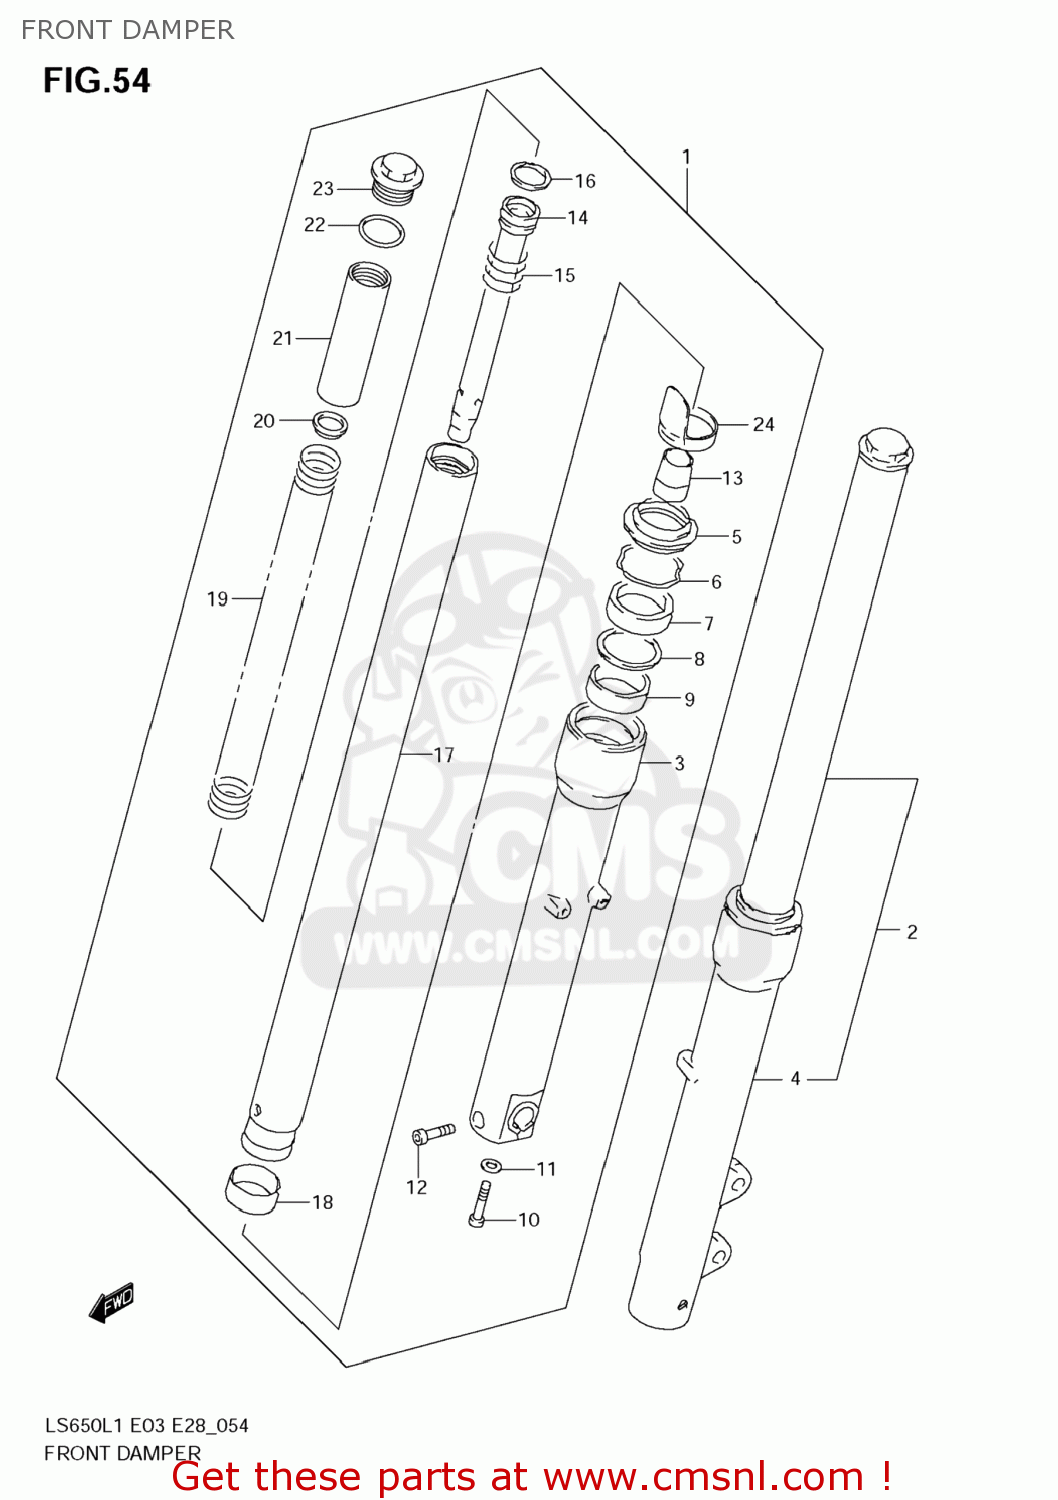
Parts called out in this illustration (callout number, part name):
1	DAMPER ASSY,FR FORK,R
2	DAMPER ASSY,FR FORK,L
3	TUBE,OUTER,R
4	TUBE,OUTER,L
5	SEAL,DUST
6	RING,STOPPER
7	SEAL,OIL
8	WASHER(40X50X2.3)
9	METAL,SLIDE
10	BOLT,FORK CYLINDER(10X25)
11	GASKET (NAS)
12	BOLT
13	PIECE,OIL LOCK
14	CYLINDER
15	SPRING,REBOUND
16	RING,PISTON
17	TUBE,INNER
18	PISTON
19	SPRING
20	WASHER
21	SPACER,SPRING
22	O RING
23	CAP
24	PROTECTOR,FR FORK
